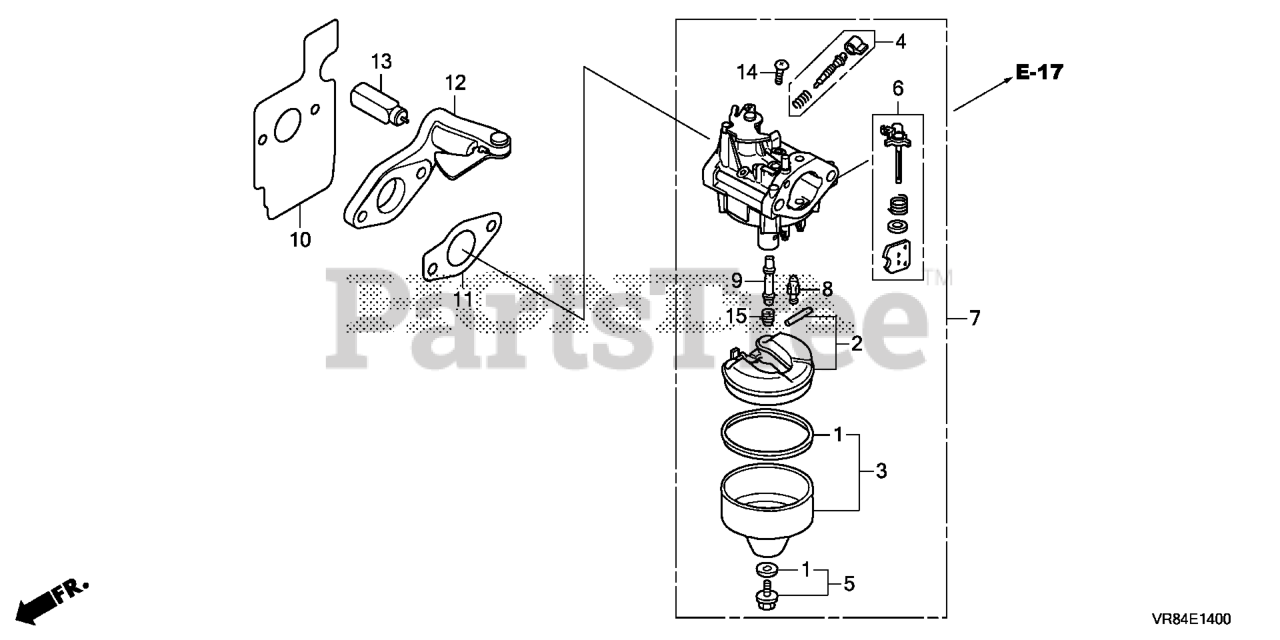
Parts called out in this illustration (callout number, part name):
1	GASKET SET
2	FLOAT SET
3	CHAMBER SET, FLOAT
4	SCREW SET (CARBURETOR NO.)
5	SCREW SET
7	CARBURETOR ASSY. (BB76J A)
8	VALVE, FLOAT (Honda Code 7934714). (CARBURETOR NO.)
9	NOZZLE, MAIN
10	GASKET, INSULATOR
11	GASKET, CARBURETOR
12	CONTROL ASSY., CHOKE
13	THERMO WAX ASSY.
14	SCREW, PAN (5X6)
15	JET, MAIN (#62) (Honda Code 0635482). (CARBURETOR NO.)
15	JET, MAIN (#65) Use up to Engine SN BB30A D.
15	JET, MAIN (#68) Use up to Engine SN BB30A D.
